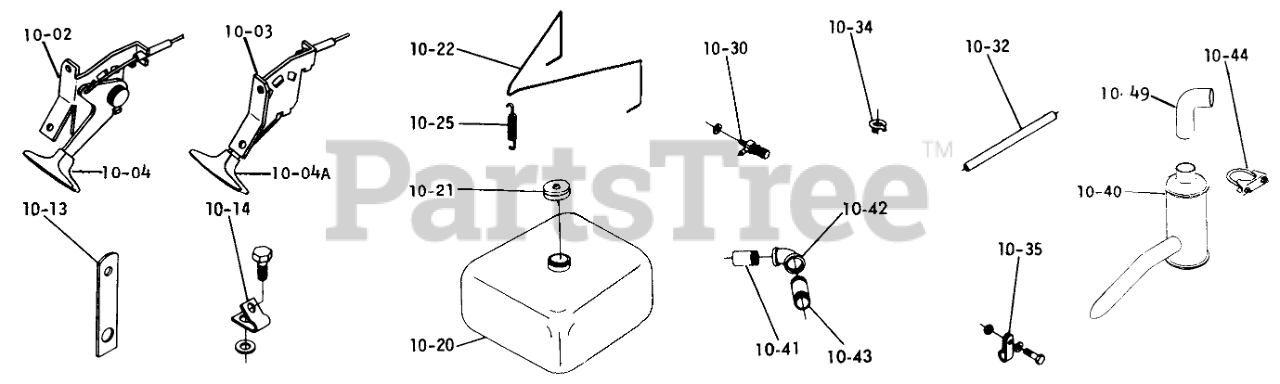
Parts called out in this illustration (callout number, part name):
10-03	THROTTLE CONTROL
10-04	KNOB-CHOKE
10-04A	KNOB-THROTTLE
10-14	THROTTLE CONTROL CLP
10-22	HOLD DOWN WIRE
10-30	VALVE-FUEL
10-40	MUFFLER
10-41	Nipple 1" x 1 1/2
10-42	Elbow 90 X 1
10-43	Nipple-1" Special (1-0385)
10-44	ASSY-MUFFLER CLAMP
